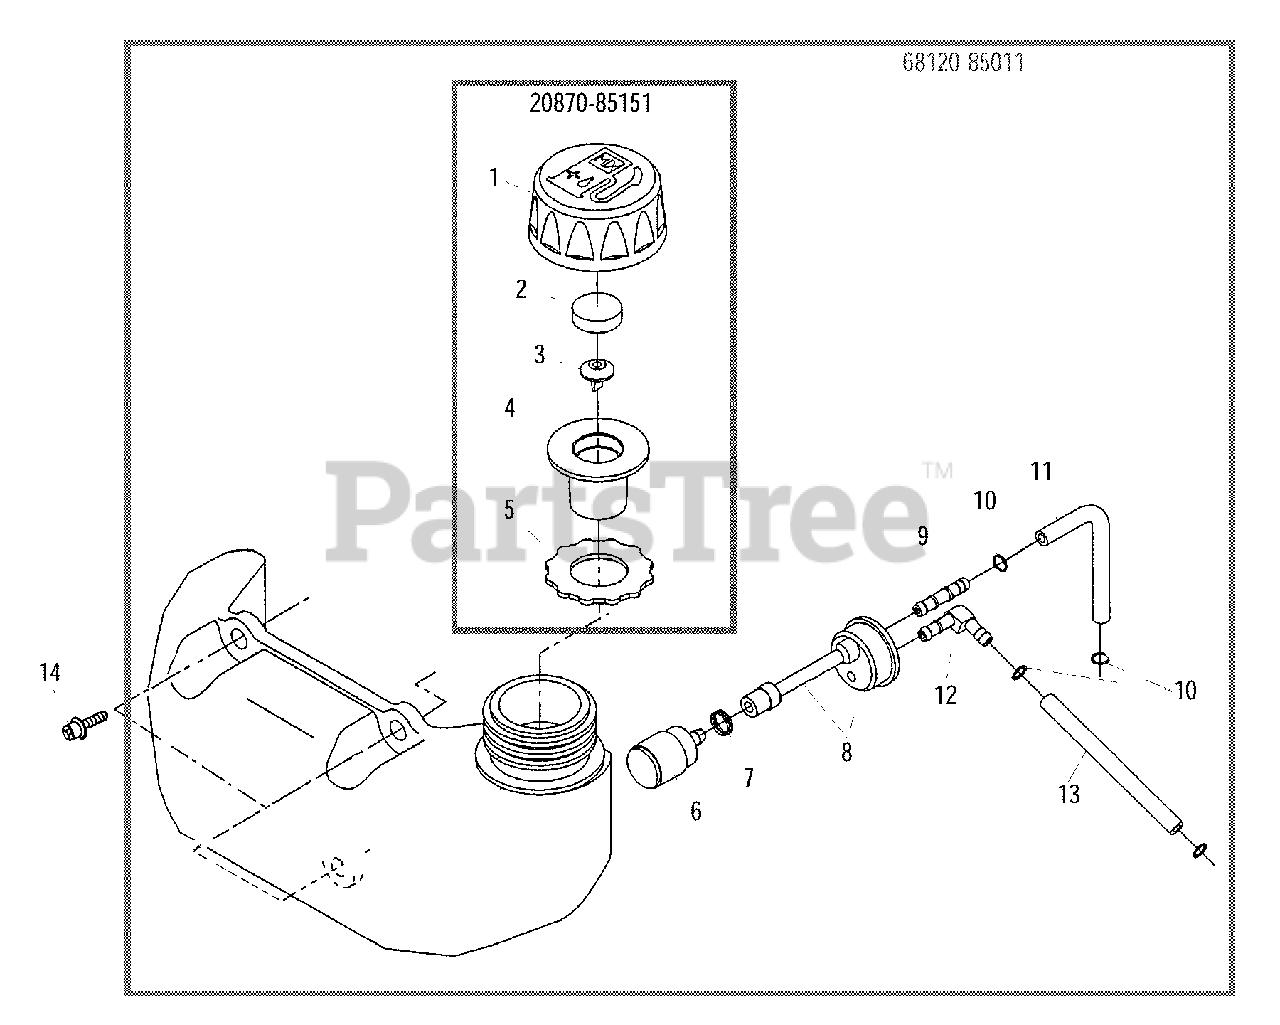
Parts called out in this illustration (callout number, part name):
1	CAP ASSY
2	COVER, VENT
3	VENT, FUEL TANK
4	HOLDER, VENT
5	GASKET, CAP
6	FILTER, FUEL
7	RING, RETAINING
8	FUEL PIPE ASSY
9	CONNECTOR, PIPE
10	RING, RETAINING - 6
11	PIPE - FUEL
12	CONNECTOR, PIPE
13	PIPE - RETURN
14	SCREW - 5X20
20870-85151	CAP ASSY
68120-85011	FUEL TANK ASSY
